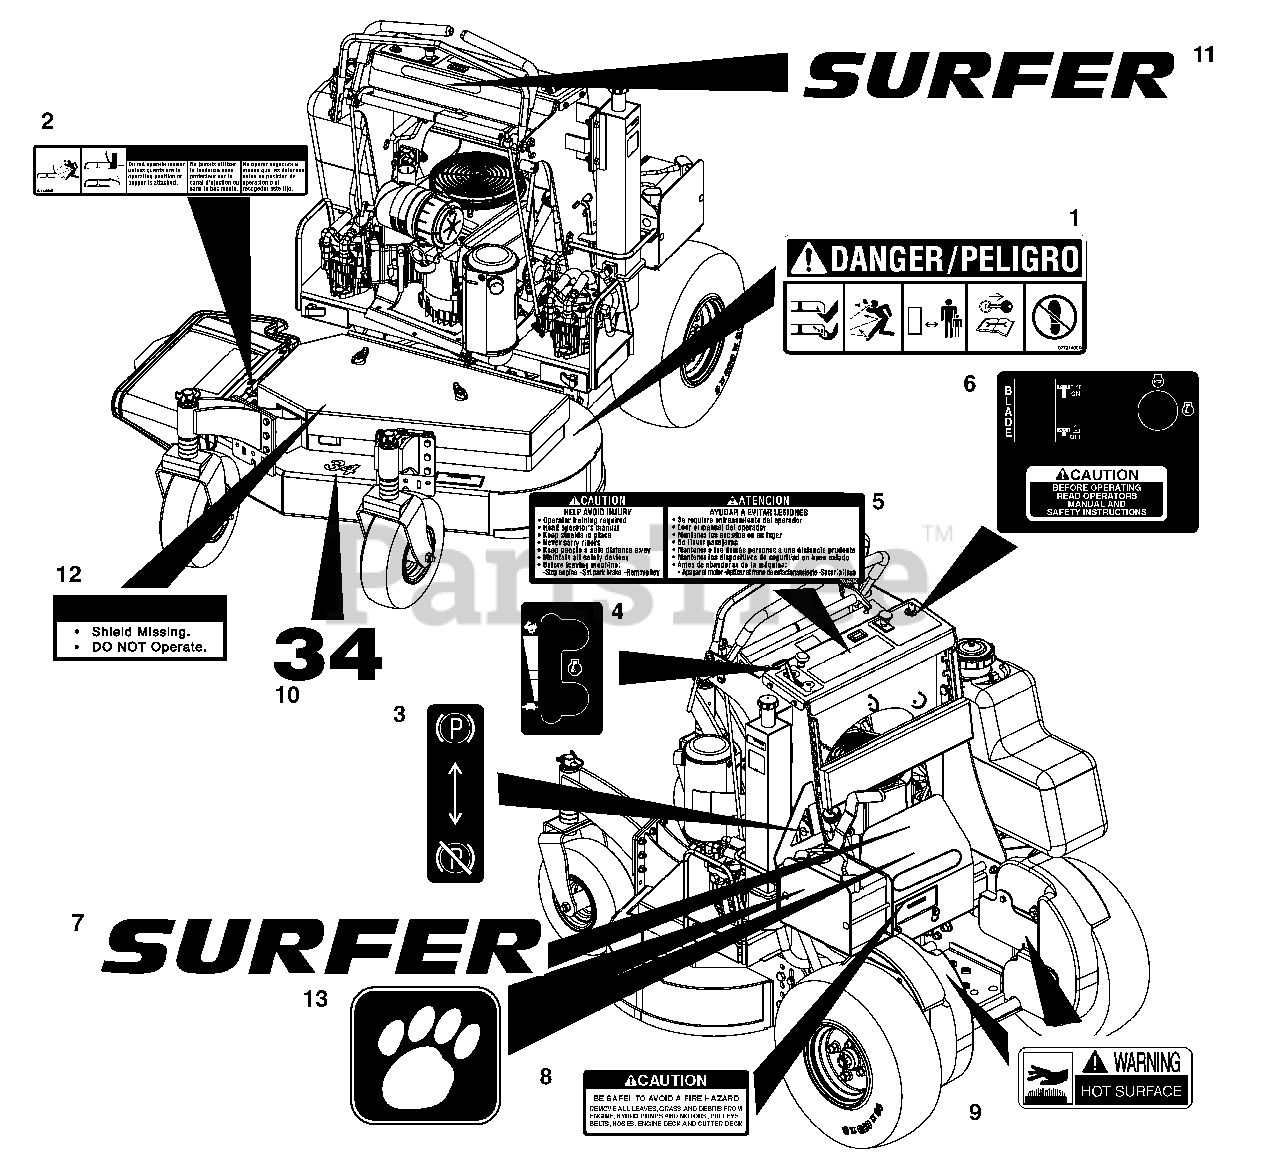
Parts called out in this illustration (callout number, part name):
1	Decal, Mower Pan Danger
2	Decal, Warning
3	Decal, Park Brake
4	Decal, Throttle
5	Decal, General Caution
6	Decal, PTO/Ignition
7	Decal, Surfer 10.5"
8	Decal, Caution - Fire Hazard
9	Decal, Warning, Hot Surface
10	Decal, 34"
11	Decal, Surfer 7.5"
12	Decal, Warning - Shield
13	Decal, Paw Print
